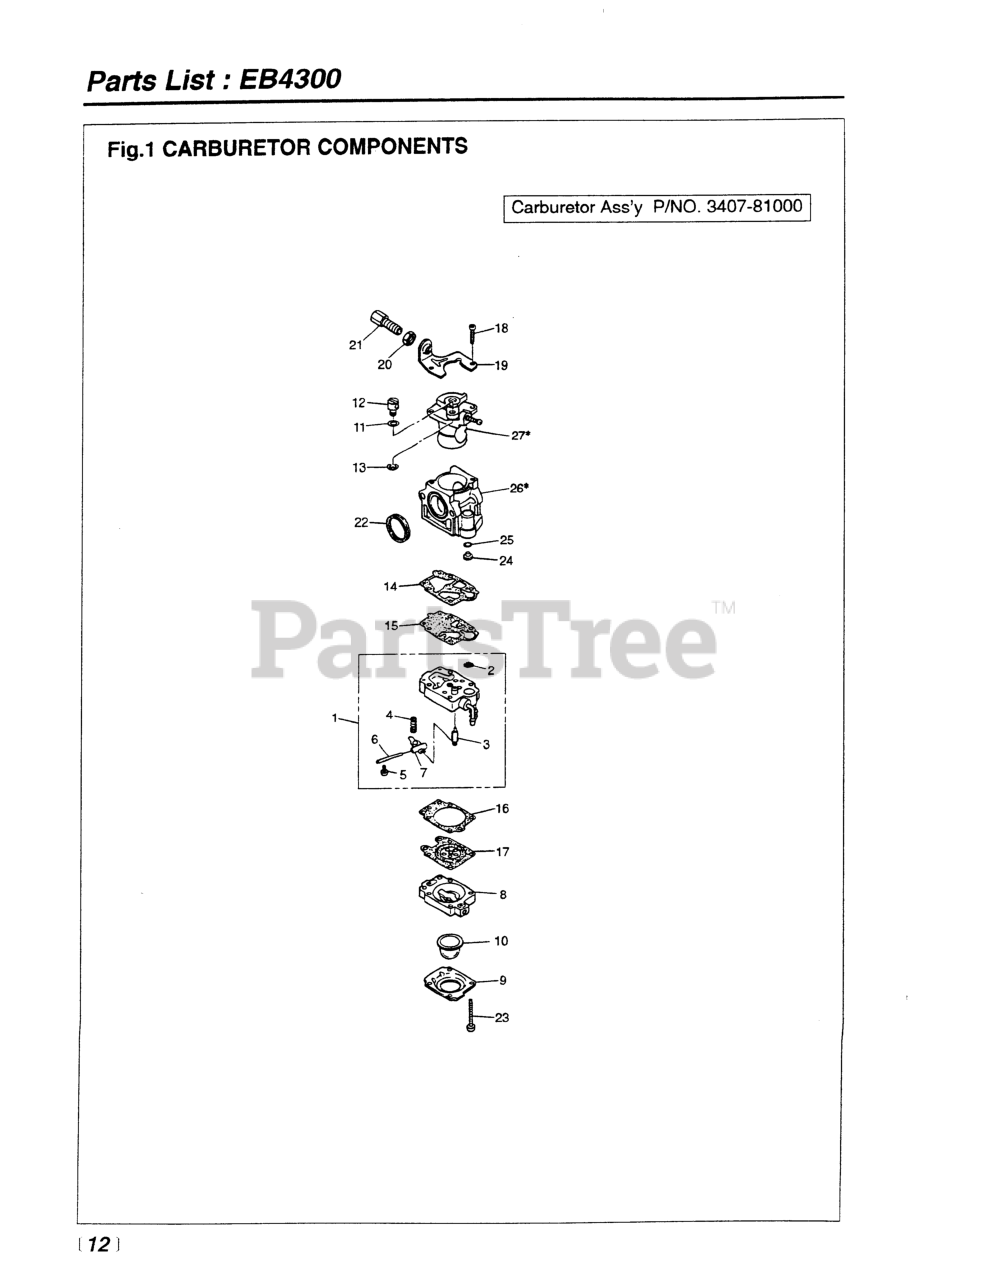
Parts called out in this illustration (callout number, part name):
1	BODY, PUMP
3	VALVE, INLET
4	SPRING, METERING LEVER
5	SCREW, METERING LEVER PIN
6	PIN, METERING LEVER
7	LEVER
8	BODY, PURGE
9	COVER, PUMP
10	PUMP, PRIMING
11	WASHER
12	SWIVEL
13	RING
14	GASKET, PUMP
15	DIAPHRAGM
16	GASKET, DIAPHRAGM
17	DIAPHRAGM (USE 4810-81260)
18	SCREW
20	NUT, CABLE ADJUSTER
21	SCREW, CABLE ADJUSTER
22	RING, PACKING
23	SCREW
25	RING, O
26	CARBURETOR ASSEMBLY
27	CARBURETOR ASSEMBLY
